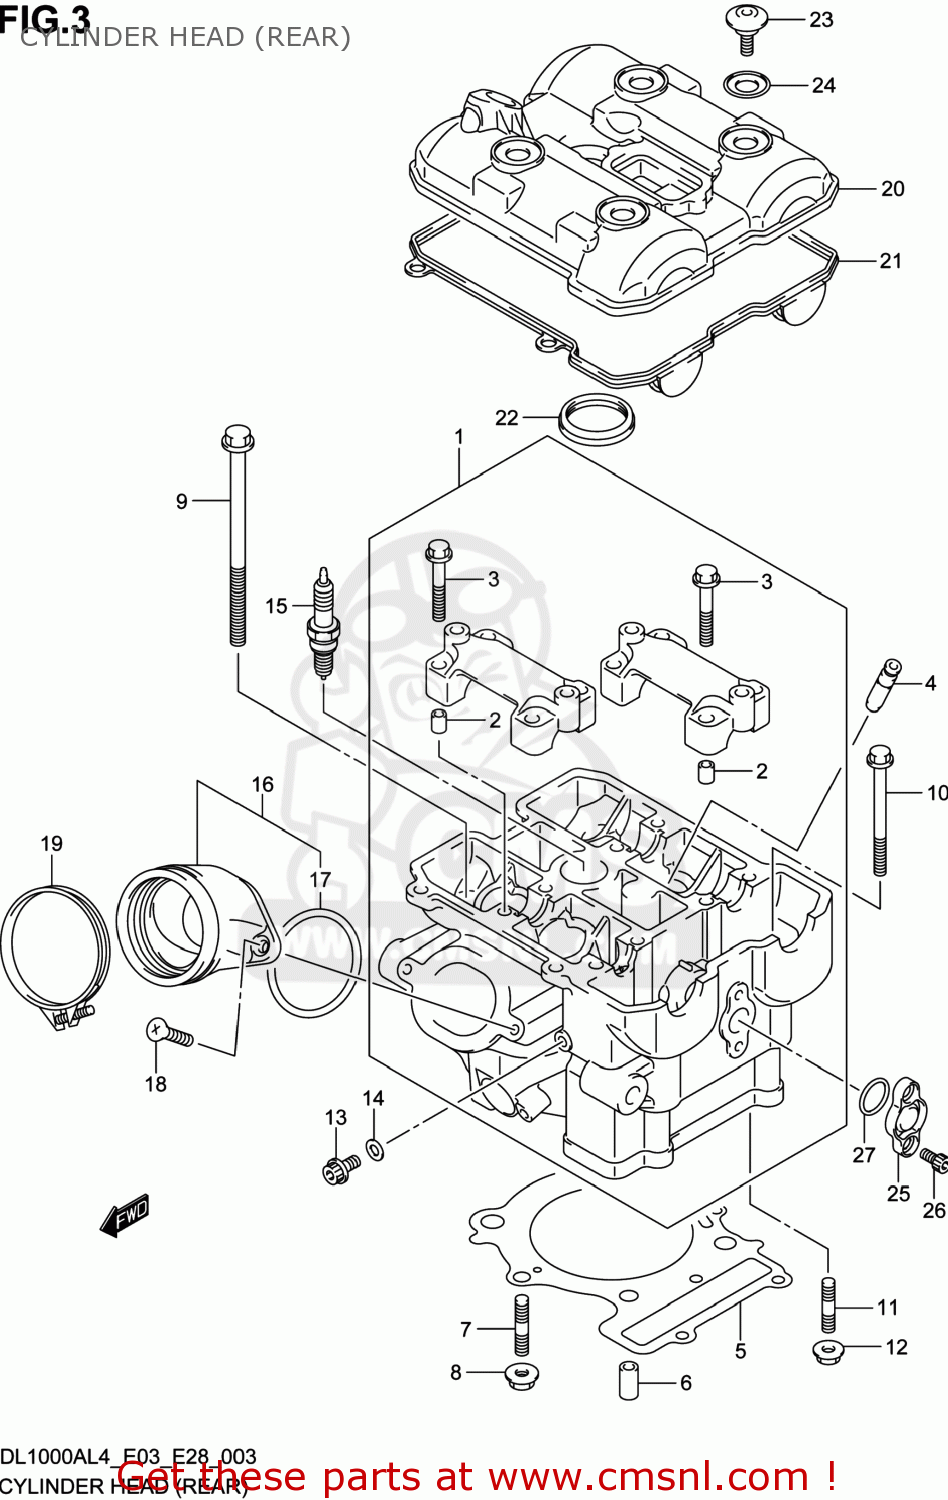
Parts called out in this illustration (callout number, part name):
1	HEAD ASSY,CYLINDER FRONT
2	PIN(6.2X8X11)
3	BOLT(6X40)
4	GUIDE,VALVE
5	GASKET,CYLINDER HEAD (NAS)
6	PIN
7	BOLT,STUD
8	NUT
9	BOLT,CYLINDER HEAD(L:165)
10	BOLT(6X60)
11	BOLT,STUD
12	NUT
13	BOLT(6X12)
14	GASKET(5.8X13X1.2) (NAS)
15	PLUG,SPARK(LMAR8BI-9)
16	PIPE ASSY,INTAKE REAR
17	O RING(D:2.4,ID:55.6)
18	SCREW
19	CLAMP,INTAKE PIPE
20	COVER,CYLINDER HEAD REAR
21	GASKET,CYL HEAD COVER NO.1 (NAS)
22	GASKET,CYL HEAD COVER NO.2
23	BOLT(7X17.5)
24	WASHER,CYL HEAD COVER
25	COVER,CYL HEAD NO.2
26	BOLT(6X12)
27	O RING(D:2.4,ID:19)
